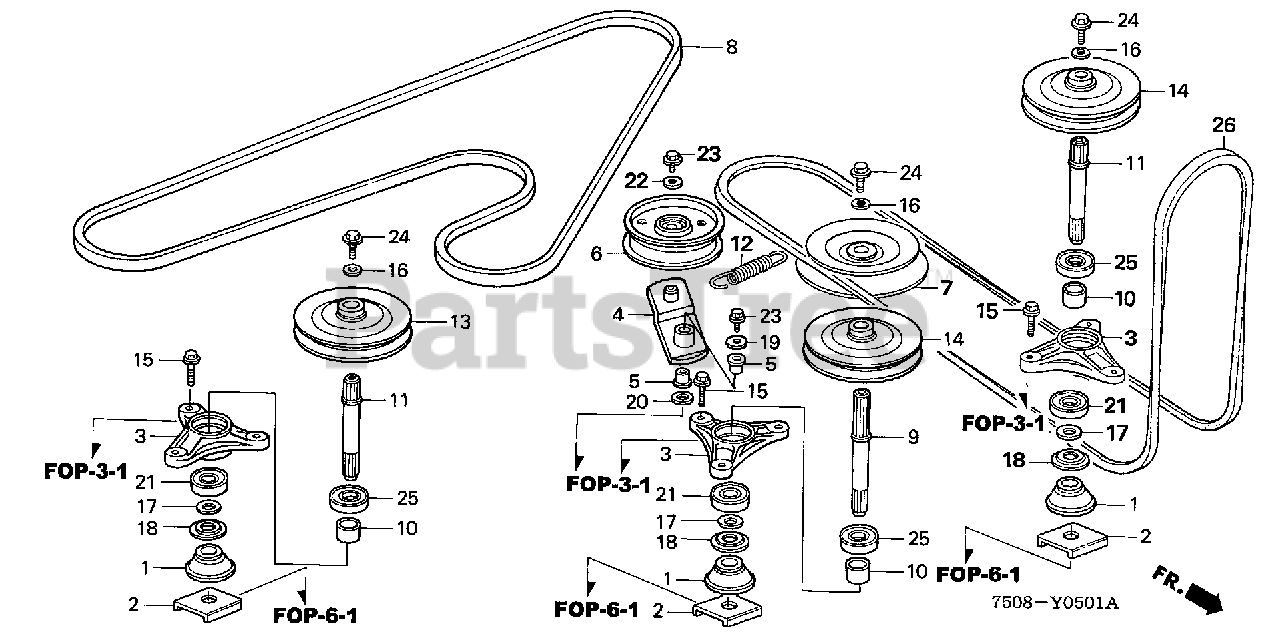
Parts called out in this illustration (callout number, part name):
1	HOLDER, BLADE
2	HOLDER, BLADE (B)
3	HOUSING, BEARING
4	ARM, TENSIONER
5	BUSH, TENSIONER ARM (15X19X14)
6	ROLLER, TENSIONER
7	PULLEY, DRIVEN
8	V-BELT, BLADE (76'')
9	SHAFT C, BLADE
10	COLLAR, BLADE SHAFT
11	SHAFT, BLADE
12	SPRING, TENSIONER ARM (BLADE)
13	PULLEY, R. DECK
14	PULLEY, DECK
15	BOLT, FLANGE (10X28)
16	WASHER (10.5X27)
16	WASHER (10.5X27X4)
17	WASHER, THRUST (20MM)
18	WASHER, BLADE HOLDER
19	WASHER (8MM)
20	WASHER, PLAIN (17.2MM)
21	BEARING, RADIAL BALL
22	WASHER, PLAIN (6MM)
23	BOLT, FLANGE (6X12)
24	BOLT, FLANGE (10X16)
25	BEARING, RADIAL BALL (6204UU)
26	V-BELT, DECK (87")
